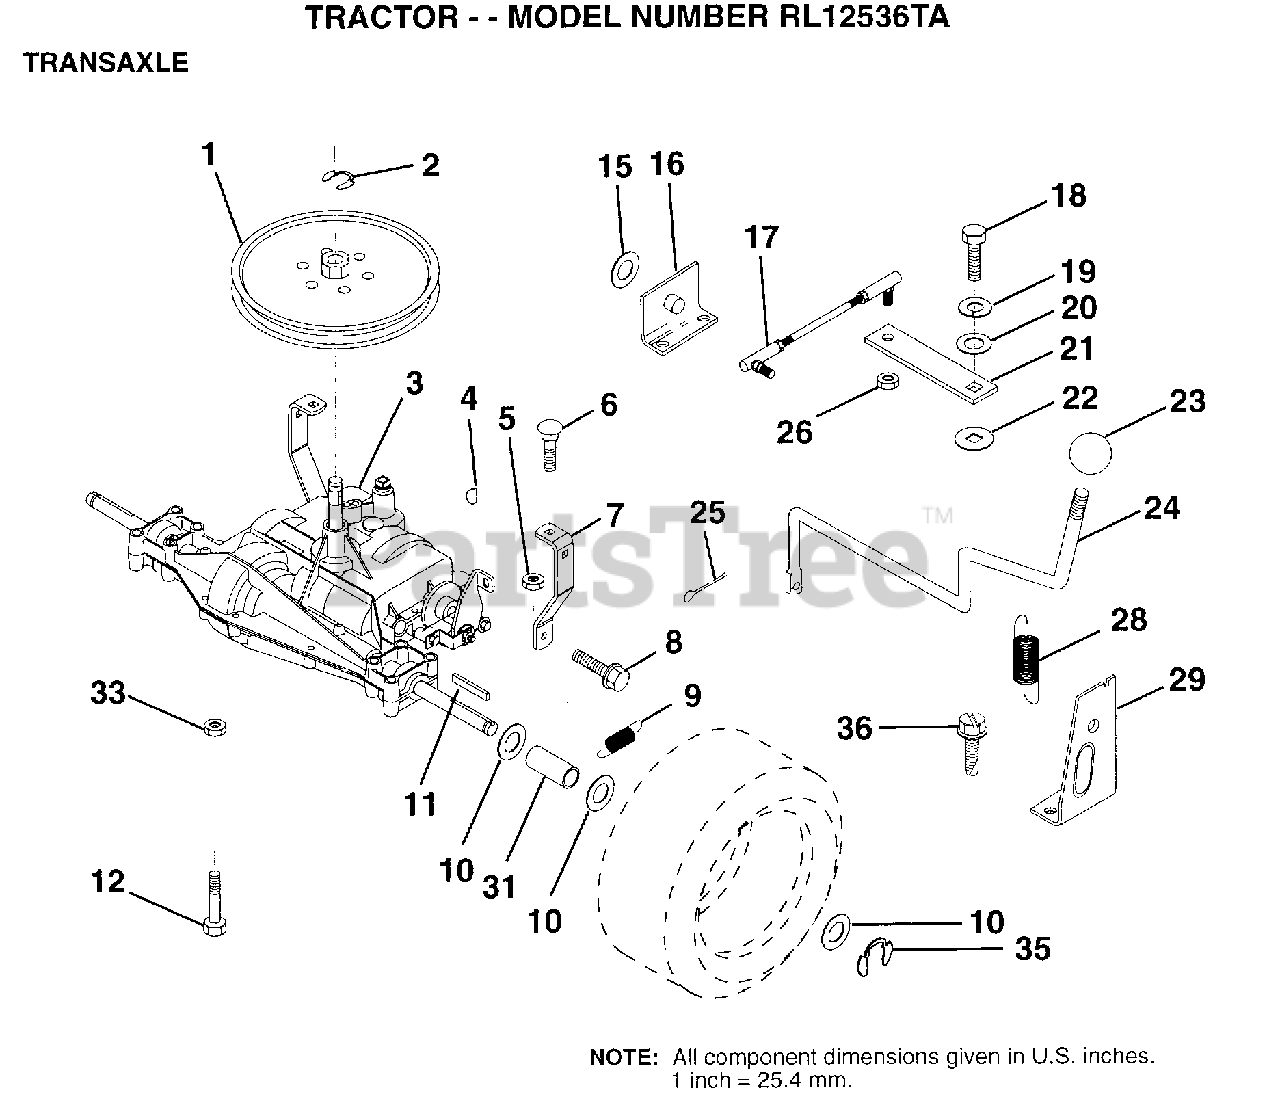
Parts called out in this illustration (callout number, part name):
1	PULLEY
6	BOLT
7	"STRAP,TORQUE"
8	SCREW
9	SPRING.BRAKE.RETU
10	WASHER
11	SQUARE KEY
12	BOLT
16	"SUPT,HDLE SHT LH"
17	"LINK,SHIFT"
18	BOLT.1/4-28.W/PAT
19	LOCKWASHER
20	WASHER LT
21	ARM SHIFT
22	WASH-SHFT PLT LT
23	KNOB T (1/2-HOLE)
24	"ROD,SHIFT"
25	PIN COTTER 1/8
26	NUT.LOCK.5/16-24
28	"SPRING,EXT"
29	"SUPT,HDLE RH"
31	SPACER LT
35	E-RING LT
36	SCREW
